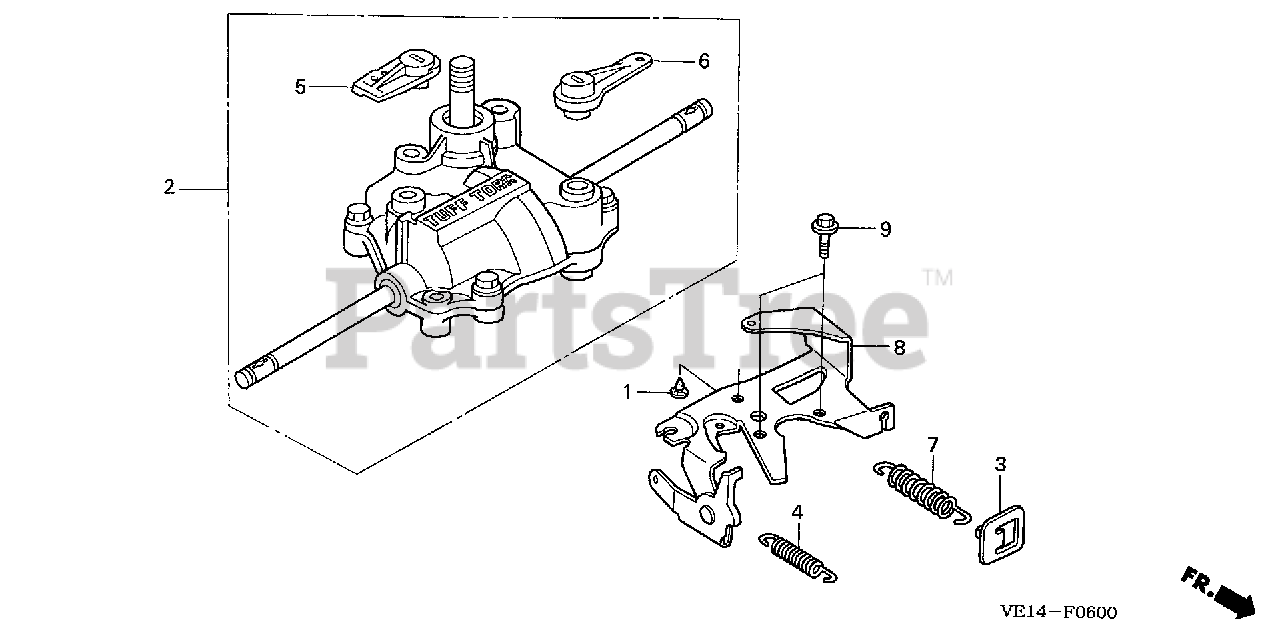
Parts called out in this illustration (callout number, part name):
1	RUBBER, TANK STOPPER
2	TRANSMISSION KIT
3	PLATE, TENSION SPRING
4	SPRING, BALL CLUTCH RETURN
5	ARM, CLUTCH
6	ARM, CHANGE
7	SPRING, WHEEL TENSION
8	HOLDER, WIRE
9	BOLT, FLANGE (8X16)
